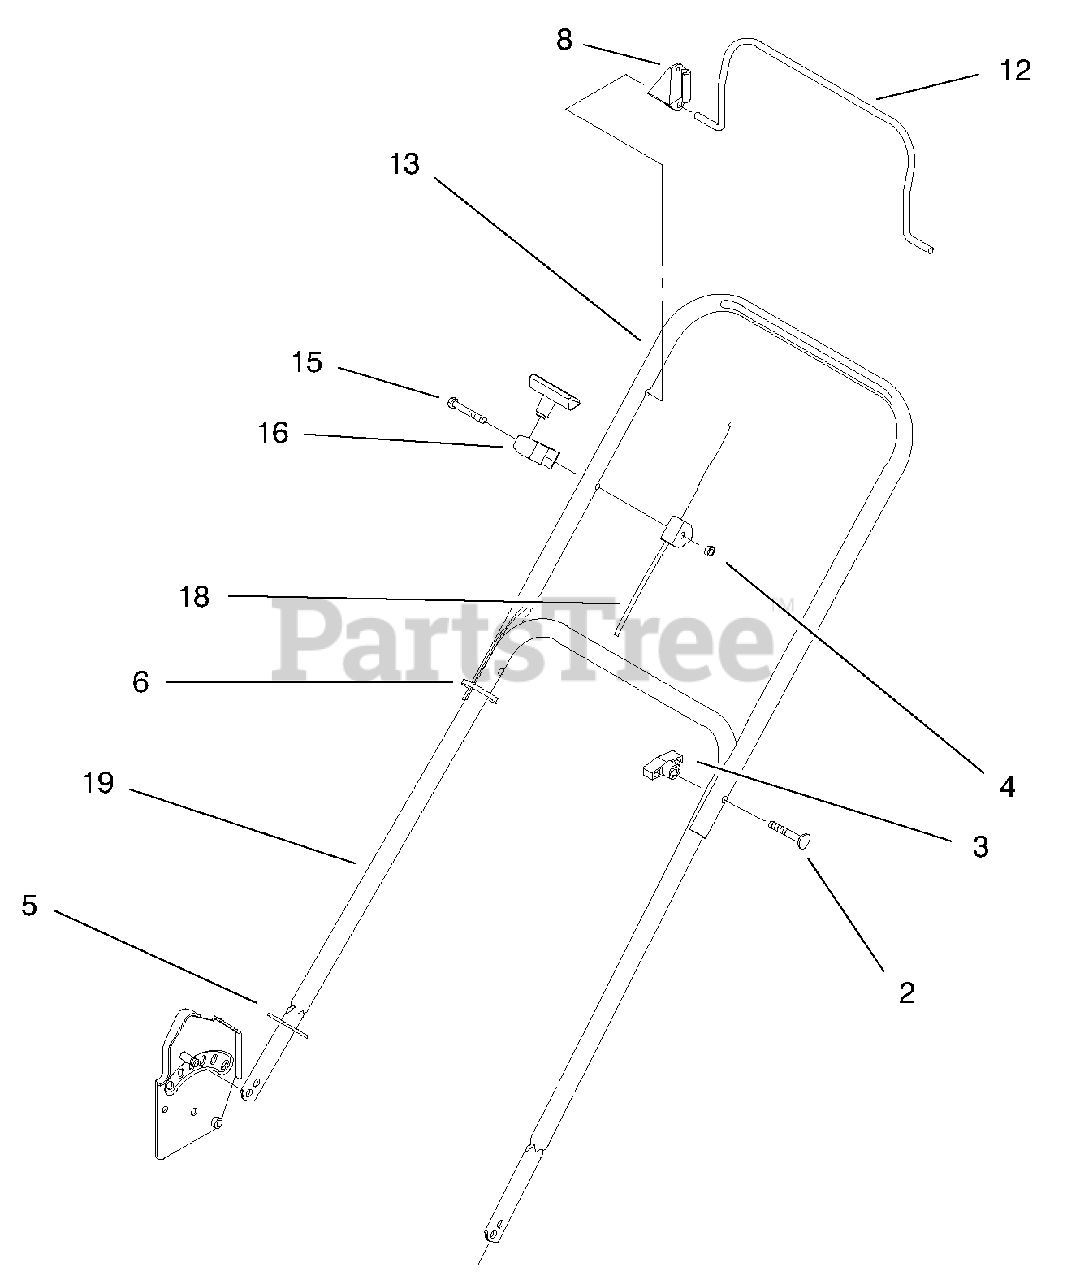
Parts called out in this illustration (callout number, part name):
2	Screw-HH
3	Knob-Handle
4	Nut-Lock
5	Guard-Handle
6	Strap-Tie Sm
8	Stop-Pivot
12	Bail-Brake
13	Handle-Upper
15	Screw-HH
16	Rope-Guide
18	ASM Brake Cable
19	Section-lower Handle
